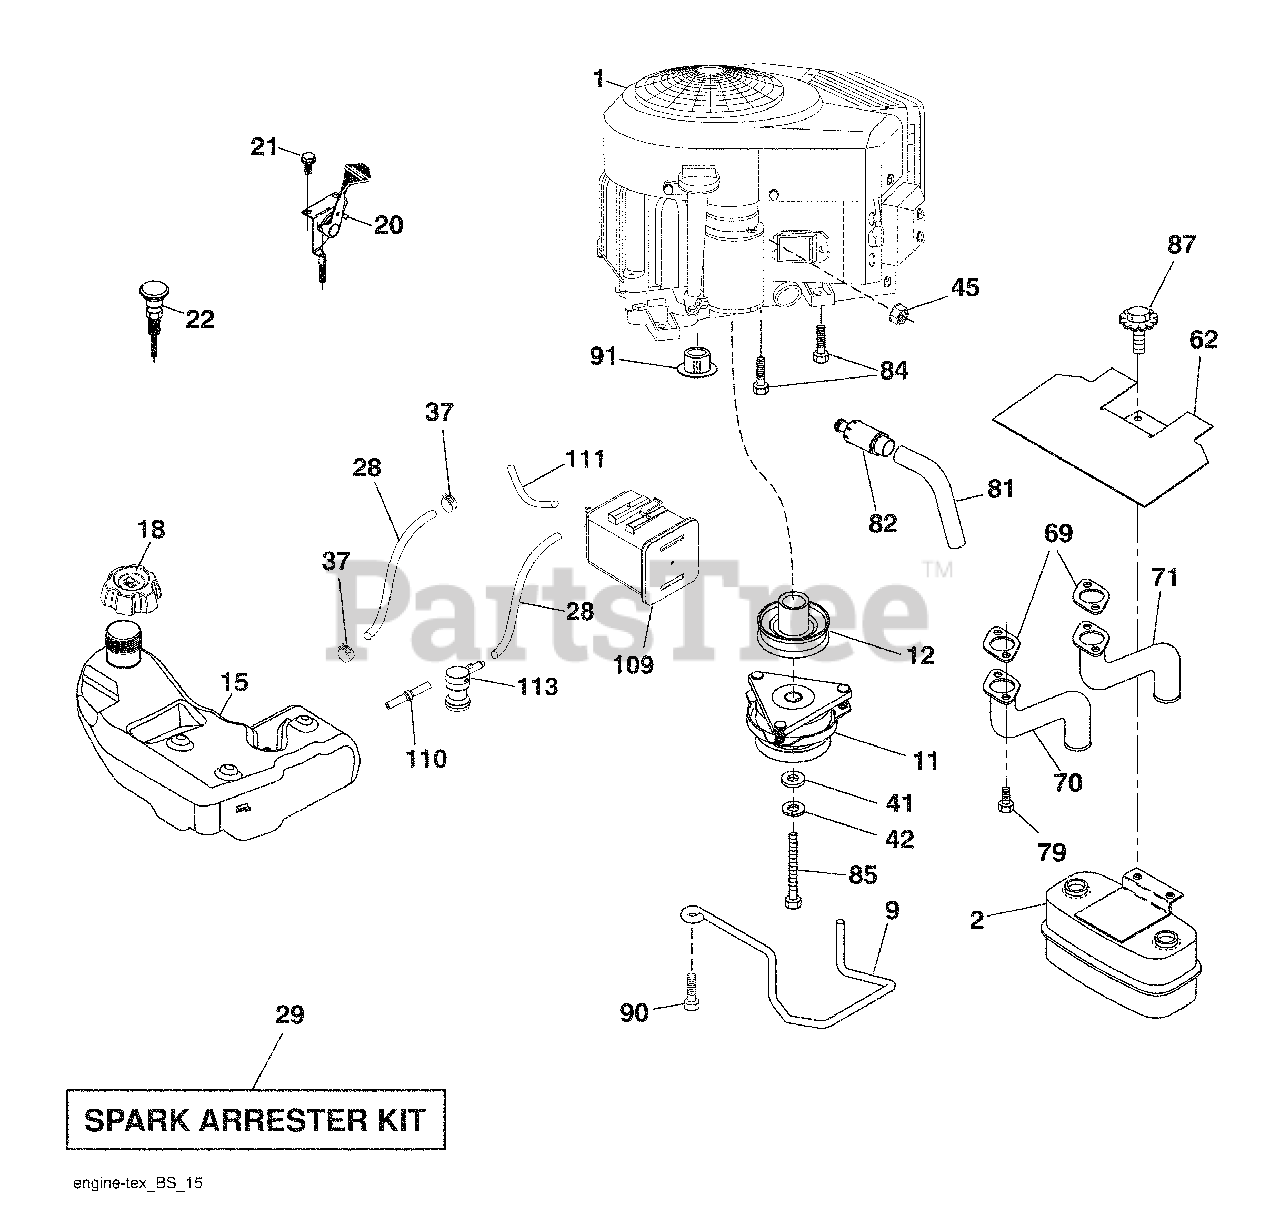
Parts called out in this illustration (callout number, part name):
9	Keeper Belt Engine
11	Clutch Electric
12	Pulley Engine
15	Tank Fuel 4.0
18	Cap Asm
20	Control Throttle
21	Screw #10 x 0.750
22	Control Choke
28	Fuel Line
29	Spark Arrester Kit
37	Clamp Hose
41	Washer 1-1/2 OD x 15/32 ID x .250
42	Washer Lock 7/16
45	Nut Keps Hex 1/4-20 unc
62	Shield Heat Muffler
70	Tube Exhaust LH
71	Tube Exhaust RH
79	Screw Socket Head 5/16-18 x 1
81	Tube Drain Oil Easy
82	Plug Drain Oil Easy
84	Screw 3/8-16 x 1-1/4
85	Bolt Hex 7/16-20 x 3.75 Gr. 5
87	Bolt 5/16-18 unc x 1 w/Sems
90	Screw 3/8-16 x 1
109	Canister Carbon Filter Asm
110	Valve Anti Slosh
111	Purge Line
113	Valve Slant Cartrdg
